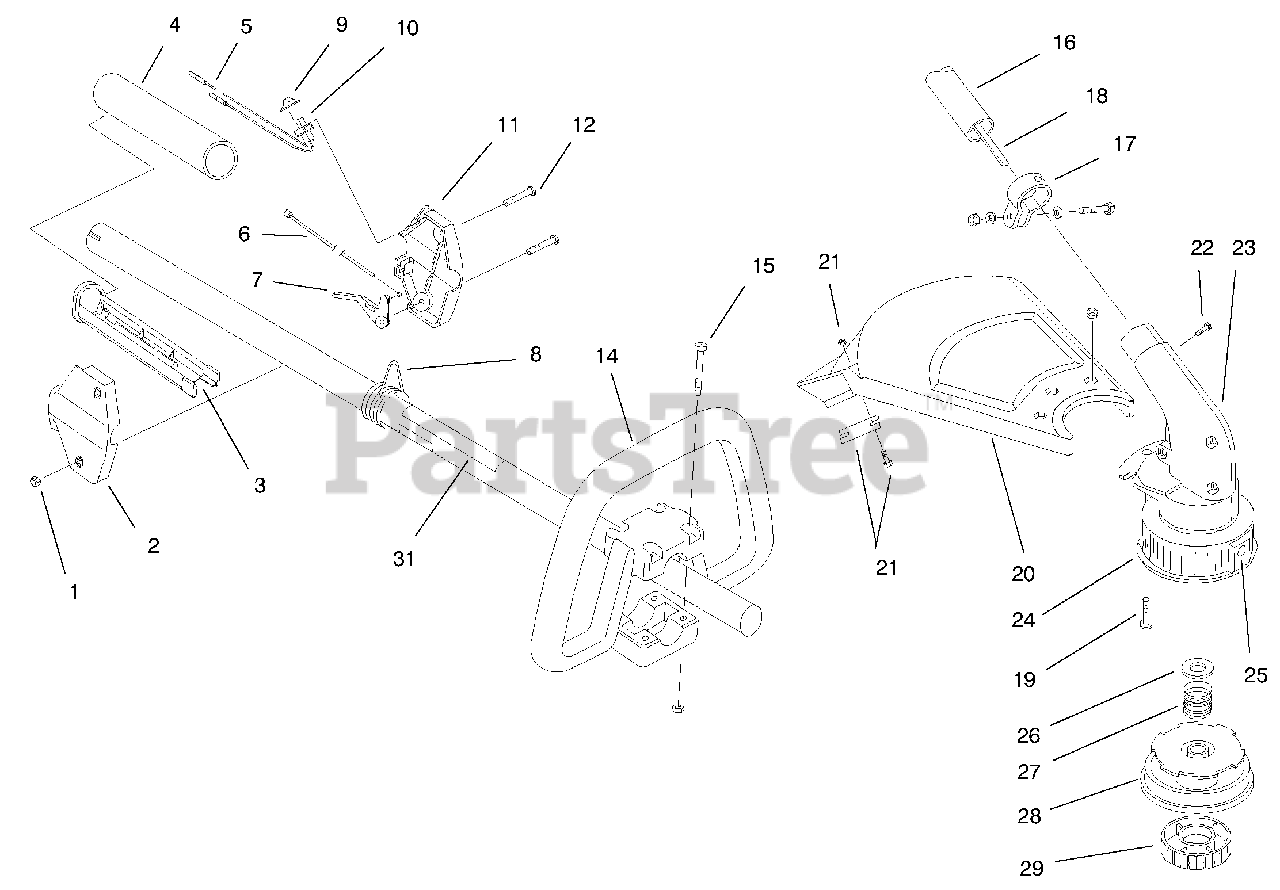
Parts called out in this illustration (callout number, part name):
1	NUT-LOCK
2	RH HOUSING
3	TROUGH 1"
4	GRIP - RUBBER
5	LEAD WIRE ASM
6	THROTTLE CABLE
7	THROTTLE LEVER
8	Clip-Shoulder Strap
9	SWITCH COVER
11	LH HOUSING
14	HANDLE W/HARDWARE
15	HARDWARE - HANDLE
16	ASM - DRIVE SHAFT HSG
17	CLAMP ASM - UPPER
18	Drive Shaft
19	ASM - GUARD MTG SCREW
20	Guard and Blade Asm.
21	BLADE ASM
22	ANTI-ROTATION SCREW
23	ASM - GEAR BOX
24	OUTER SPOOL EYELET ASM
26	RETAINER WASHER(SET OF 10)
28	REEL - INNER
29	Assy.-Bump Head
31	Decal-Safety Symbol
